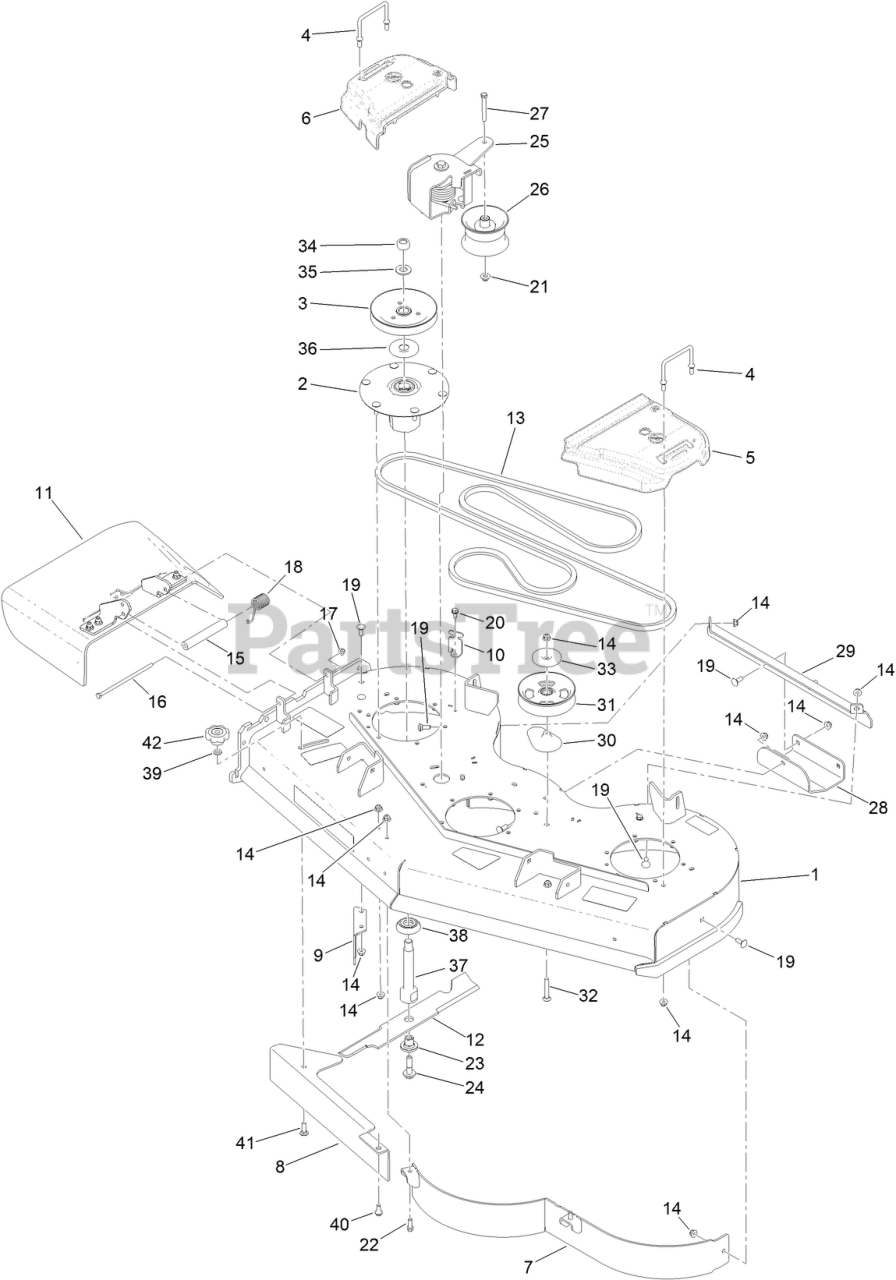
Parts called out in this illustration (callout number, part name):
1	52 DECK ASM
2	SPINDLE ASM
3	SHEAVE-BLADE, DRIVE
4	WIREFORM-COVER
5	COVER-BELT, LH
6	COVER-BELT, RH
7	BAFFLE-52 INCH
8	PLATE-BAFFLE, FORMED [RED]
9	BAFFLE-DISCHARGE
10	BRACKET-COVER
11	RUBBER DEFLECTOR ASM
12	BLADE-FLOW, HIGH
13	BELT-V
14	NUT-HF, NI
15	SPACER
16	SCREW-HH
17	NUT-HF, NI
18	SPRING-TORSION
19	BOLT-CARR
20	SCREW-HWHTF
21	NUT-FLANGE, NI
23	BUSHING-HEX
24	SCREW-SEMS
25	GS TORSION IDLER ASM II
26	PULLEY-IDLER
27	SCREW-HH
29	BRACKET-SKID
30	SPACER-PULLEY
31	PULLEY-IDLER,FLAT
32	SCREW-CARR
33	SHIELD-DUST
34	NUT-HEX
35	WASHER
36	GUARD-BEARING, TOP
37	SHAFT-SPINDLE
38	GUARD-BOTTOM
39	WASHER-HARDENED
40	BOLT-SHOULDER
41	BOLT-CARR
